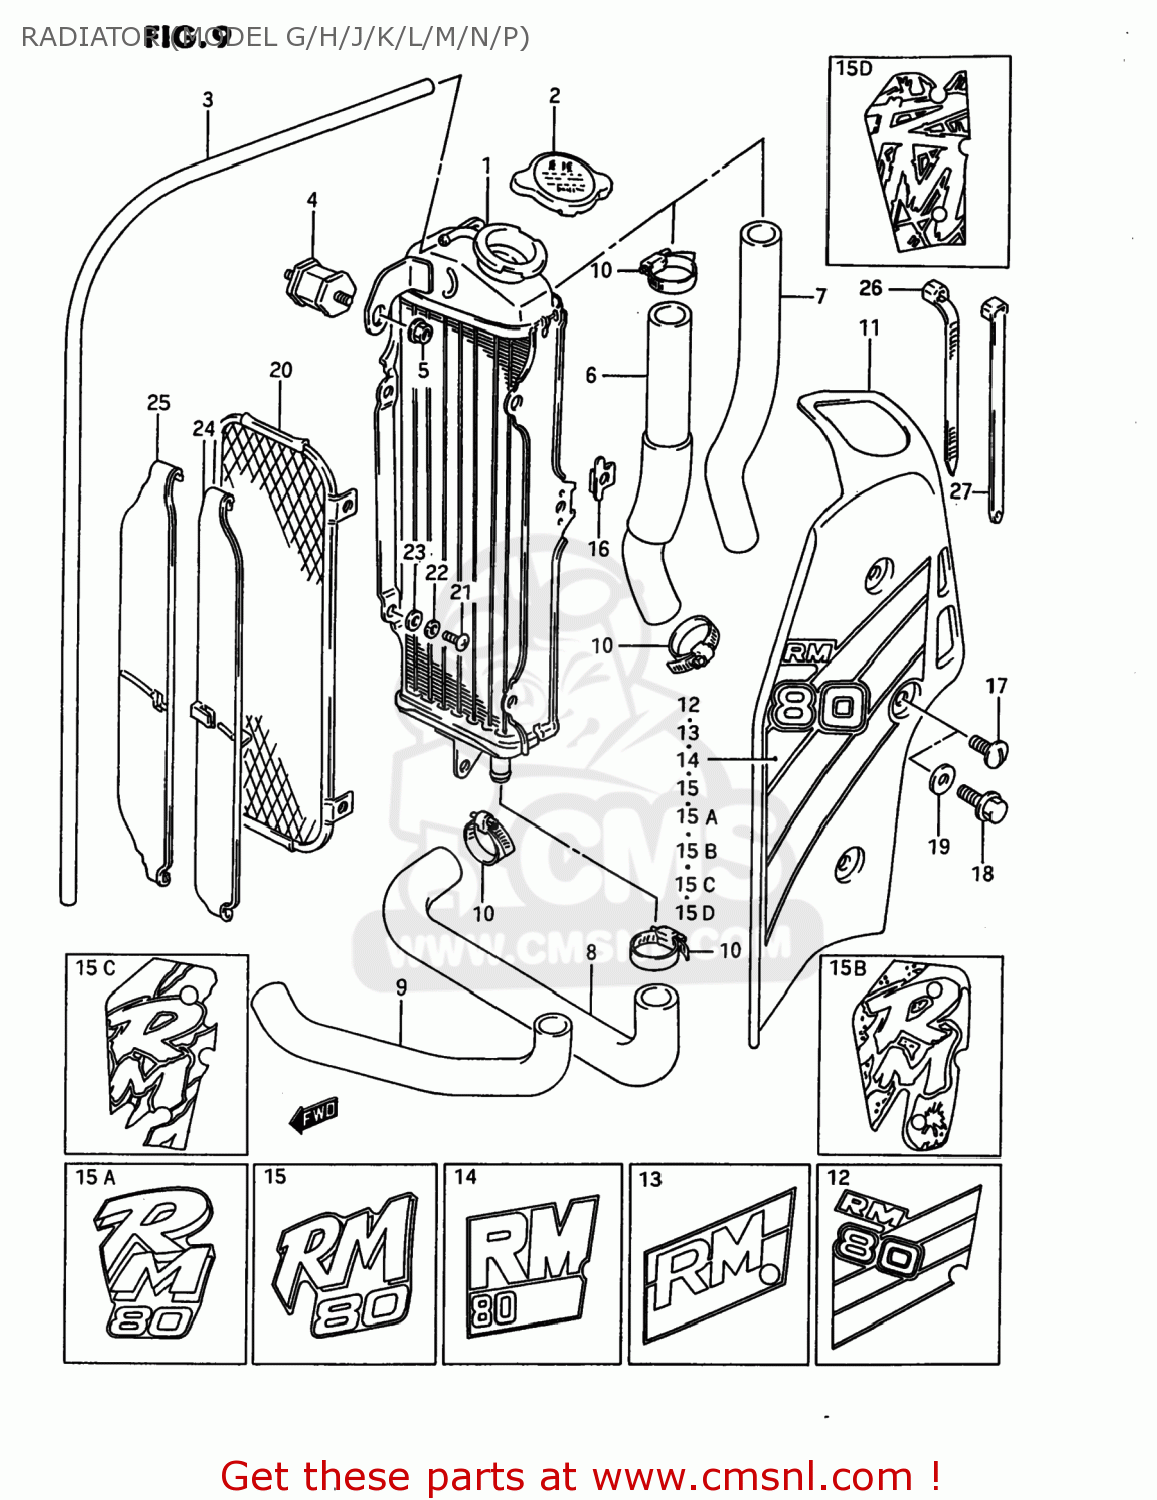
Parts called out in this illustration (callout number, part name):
1	RADIATOR COMP,WATER
2	CAP,RADIATOR 1.1
3	HOSE
4	BOLT,RADIATOR CUSHION
5	NUT 6MM
6	HOSE,RADIATOR INLET
7	HOSE,RADIATOR INLET
8	HOSE,RADIATOR OUTLET
9	HOSE,RADIATOR OUTLET
10	CLAMP
11	COVER,RADIATOR
12	TAPE SET,RADIATOR COVER
13	TAPE SET,RADIATOR COVER
14	TAPE,RADIATOR COVER
15	EMBLEM,RADIATOR COVER
15A	EMBLEM,RADIATOR COVER
15B	EMBLEM,RADIATOR COVER
15C	EMBLEM,RADIATOR COVER
15D	EMBLEM,RADIATOR COVER
16	PLATE,RADIATOR COVER FITING
17	SCREW(6X14)
18	BOLT
19	WASHER(6.5X18X1)
20	BUMPER,RADIATOR
21	SCREW
22	WASHER,LOCK
23	WASHER
24	LOUVER,RADIATOR
25	LOUVER,RADIATOR
26	CLAMP(L:165)
27	CLAMP
